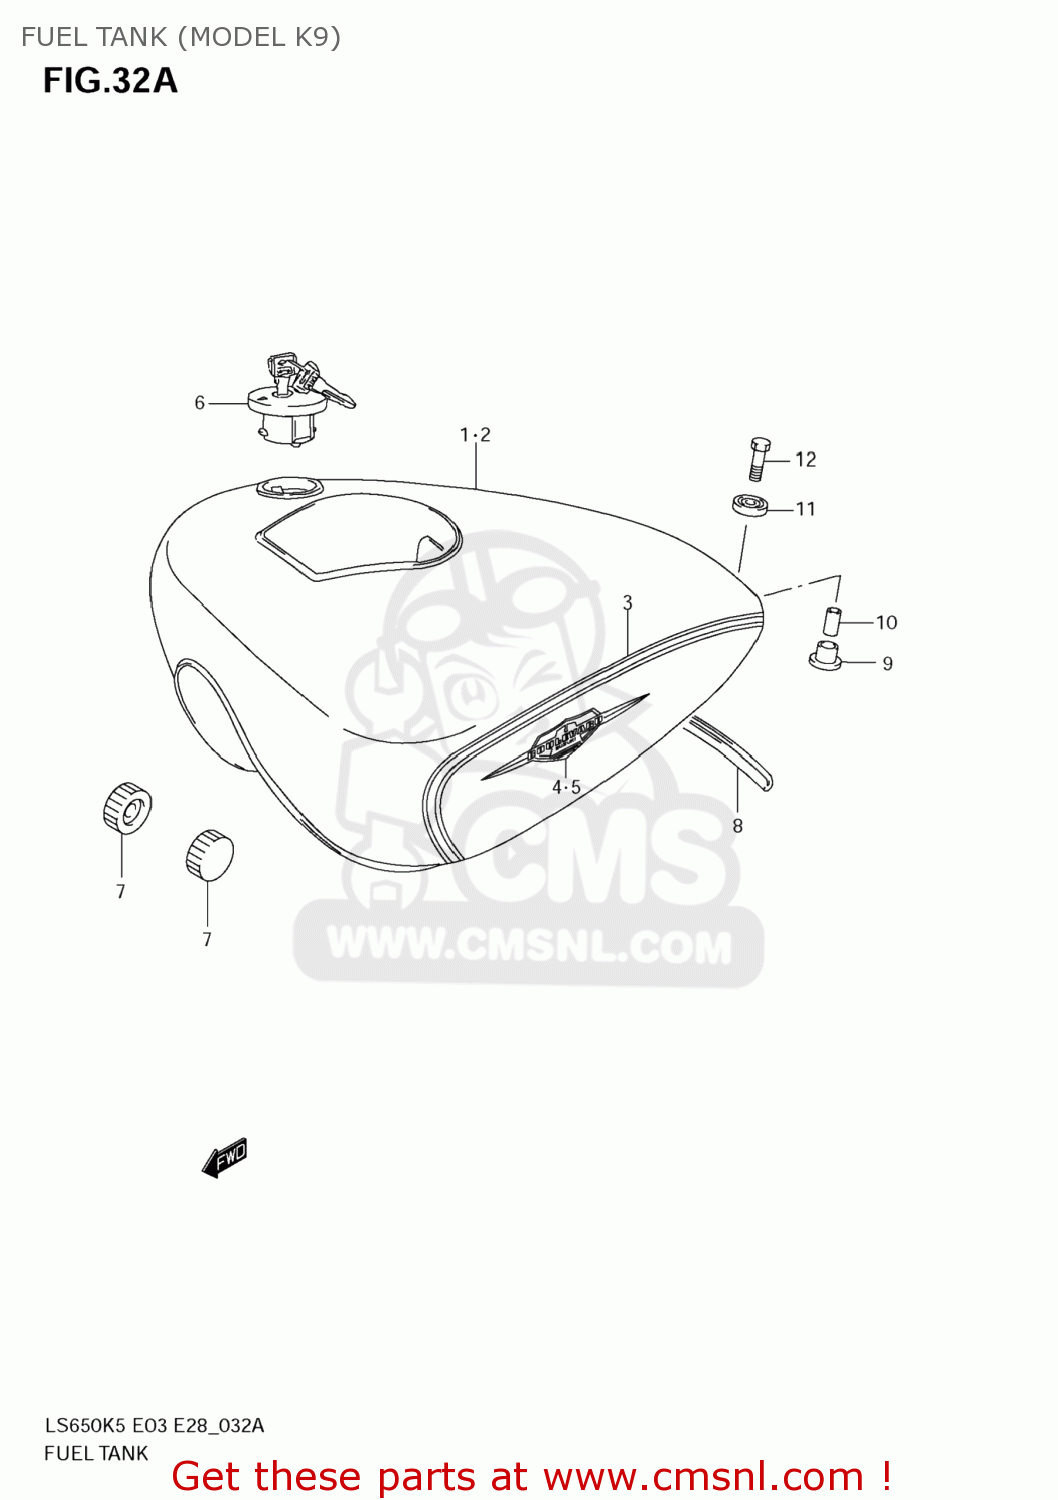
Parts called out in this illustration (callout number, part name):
1	TANK ASSY,FUEL(BLACK)
2	TANK ASSY,FUEL
3	TAPE SET,FUEL TANK
4	EMBLEM, RH
5	EMBLEM, LH
6	CAP SET,FUEL TANK
7	CUSHION
8	MOLDING,FUEL TANK RR
9	CUSHION
10	SPACER(6.5X9X18)
11	CUSHION
12	BOLT
